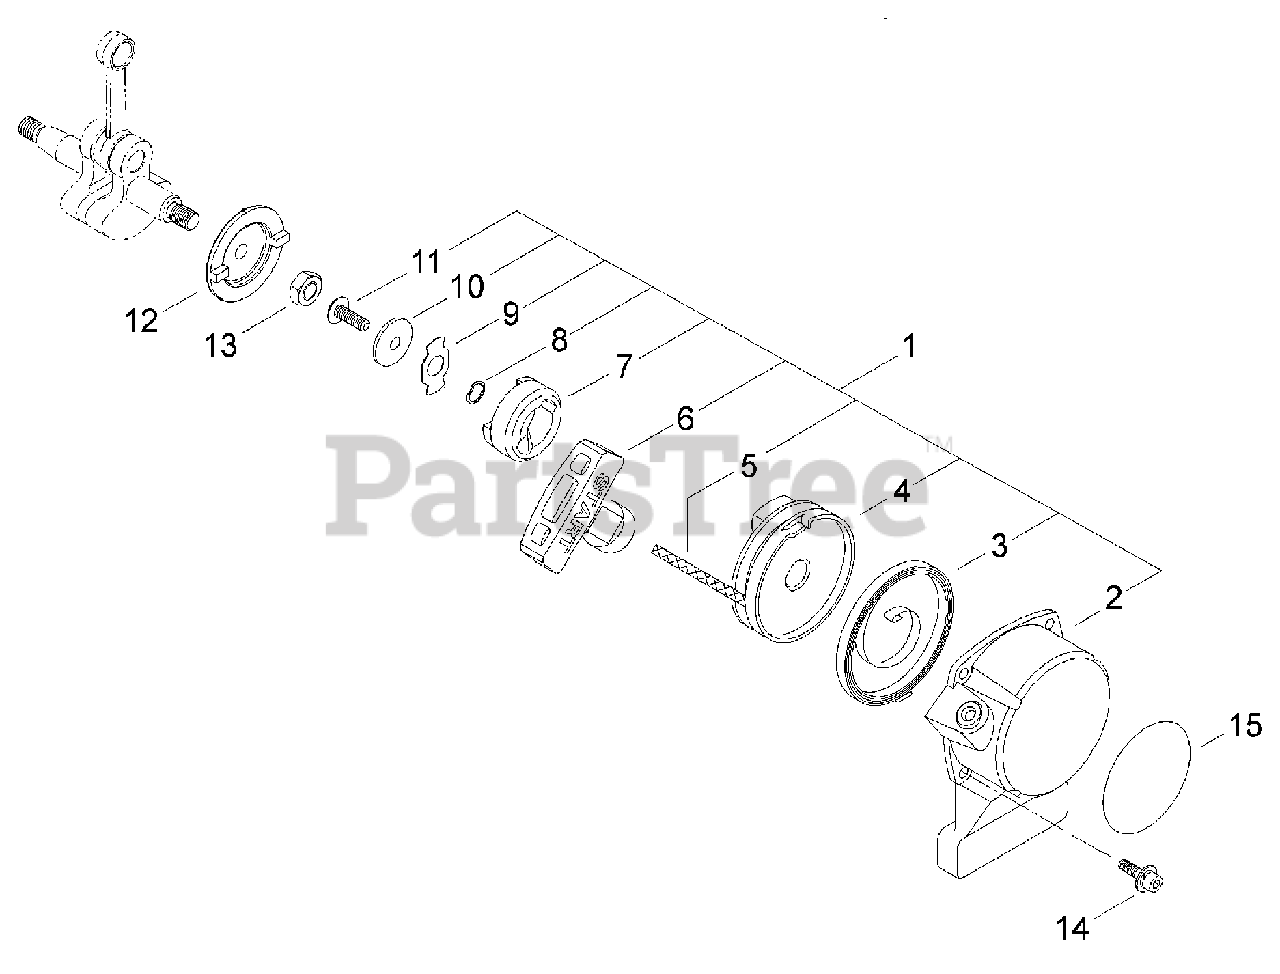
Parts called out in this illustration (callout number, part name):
1	STARTER ASSY
2	CASE, STARTER
3	SPRING, REWIND
4	REEL, ROPE
5	ROPE, STARTER
6	GRIP, STARTER
7	PAWL, STARTER
8	WASHER - SPRING
9	RETAINER
10	WASHER - 5
11	SCREW - 5
12	PAWL
13	NUT - 8
14	SCREW - 4X16
15	LABEL - E4
